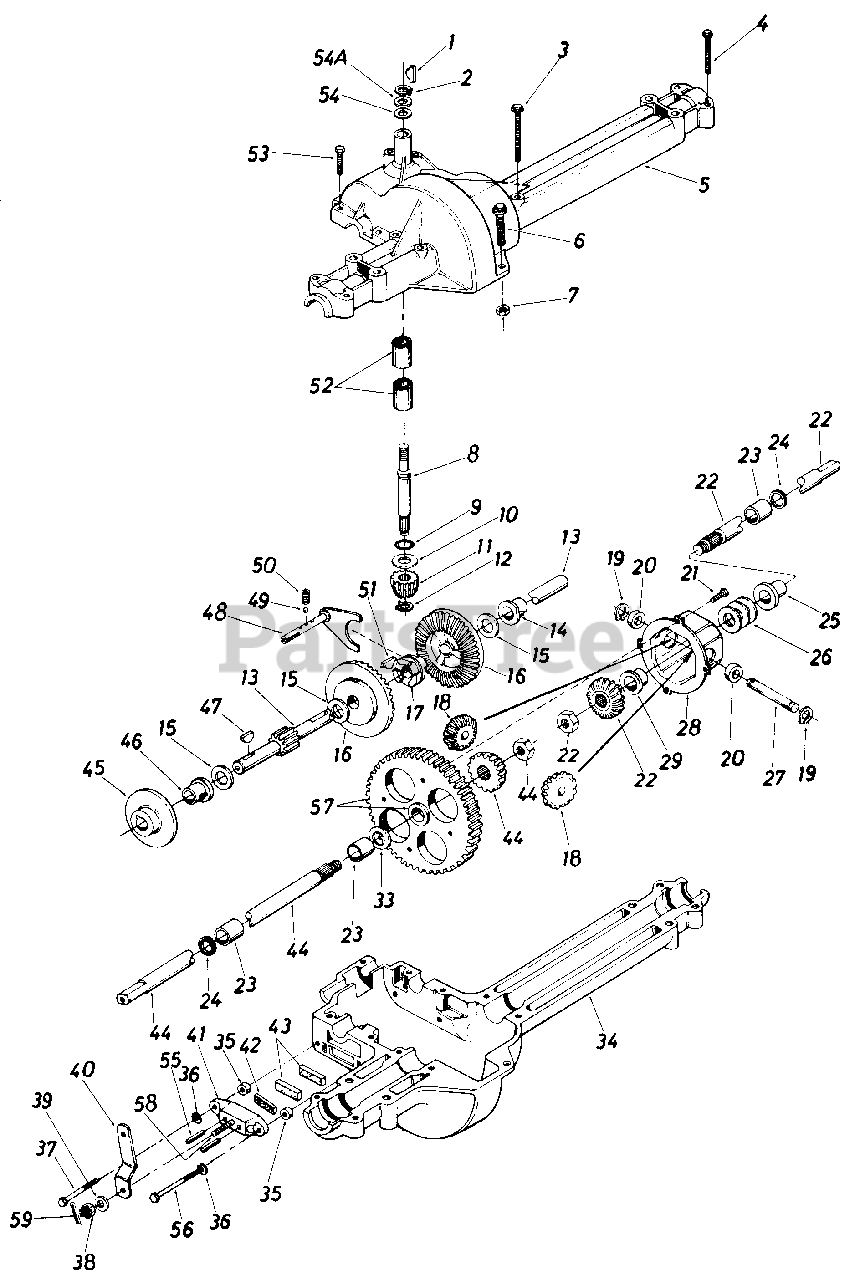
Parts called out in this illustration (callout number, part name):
1	#4 Hi-Pro Key 3/32 x 5/8" Dia.
2	Snap Ring .625" Shaft
3	Hex Bolt 1/4-20 x 1.75" Lg.
4	Hex Bolt 5/16-18 x 2.5"
5	Upper Housing
6	Hex Fl-Bolt 1/4-20 x .88" Lg.
7	Hex Nut 1/4-20 Thd.
8	Input Shaft
9	Square Seal 5/8" I.D.
10	Thrust Washer 5/8" I.D. x 1.25" O.D.
11	Pinion Input 14T
12	Retaining Ring 7/16" Ext.
14	Flange Brg. 5/8" I.D. x 3/4" Lg.
15	Fl-Wash.
16	Bevel Gear 42T
17	Clutch Collar
18	Miter Gear 15T (H.D.)
19	Snap Ring
20	Thrust Bearing 1/2" l.D. x 1.0" O.D.
21	Pan Head Scr. 1/4-20 x .50" Lg. w/Patch
22	Axle R.H. Ass'y.-Kit
23	Sleeve Bearing 3/4" I.D. x 1.0" Lg.
24	Oil Seal 3/4" I.D.
25	Flange Bearing 3/4" I.D. x 15/16" Lg.
26	Fl-Wash. .760" I.D. x 1.49 0 O.D.
27	Cross Shaft
28	Differential Housing Ass'y.
33	Fl-Wash. .760" I.D. x 1.49" O.D.
34	Lower Housing
35	Spacer .53" O.D. x 3/8" Lg.
36	L-Wash. 1/4" I.D.
37	Hex Bolt 1/4-20 x 1.50" Lg. (Grade 5)
38	Castle Nut 5/16-24 Thd.
39	Fl-Wash. .344" I.D. x .875" O.D.
40	Actuating Arm
42	Puck Plate
43	Brake Puck
44	Axle L.H. Ass'y.-Kit
46	Flange Bearing 5/8" I.D. x 15/16" Lg.
47	Woodruff Key 3/16 x 5/8 HT
48	Shift Fork Ass'y.
49	Ball Detent .250" Dia.
50	Spring Detent
51	#9 Hi-Pro Key 3/16" x 3/4n Dia. HT
52	Needle Brg. 5/8" I.D. x 1/2" Lg.
53	Hex Bolt 1/4-20 x 1.00" Lg.
54	Fl-Wash. 5/8" l.D. x .030
54A	Fl-Wash . 5/8" I . D . x .040
55	Actuating Pin 5/16" Dia.
56	Hex Bolt 1/4-20 x 2.50" Lg. (Grade 5)
57	Differential Gear 72T Ass'y. w/Bearing
58	Sq. Hd. Bolt 5/16-24 Thd.
59	Cotter Pin 3/32" Dia. x .50" Lg.
